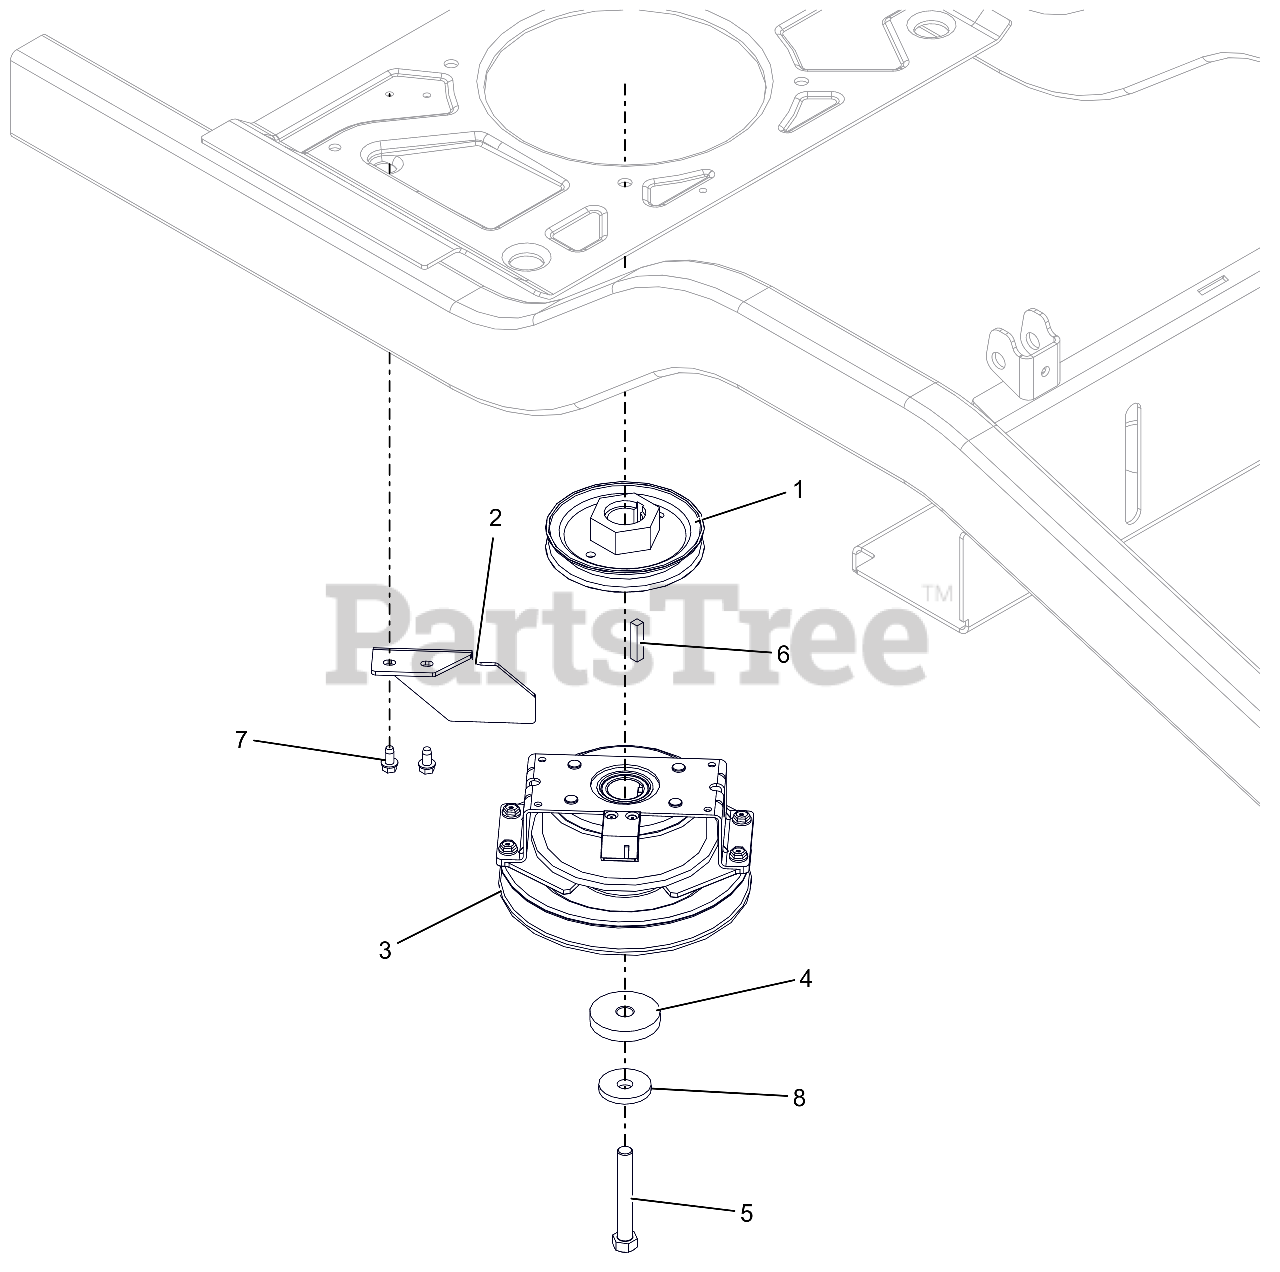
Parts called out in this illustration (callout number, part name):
1	WLDMT,PULLEY-4.50ODX1.003
2	BRKT, CLUTCH STOP HD
3	CLUTCH, OGURA DBL SPRG
4	SPACER, .474/.459X2.00X.350
5	BLT, HEX 0.4375-20X3 G8 ZCC NT
6	KEY-SQ .25 X 1.25 X .25 SAE
7	SCR-TAP .25-20X.50 HWH ZCC
8	WASHER, 7/16" SPRING DISK
